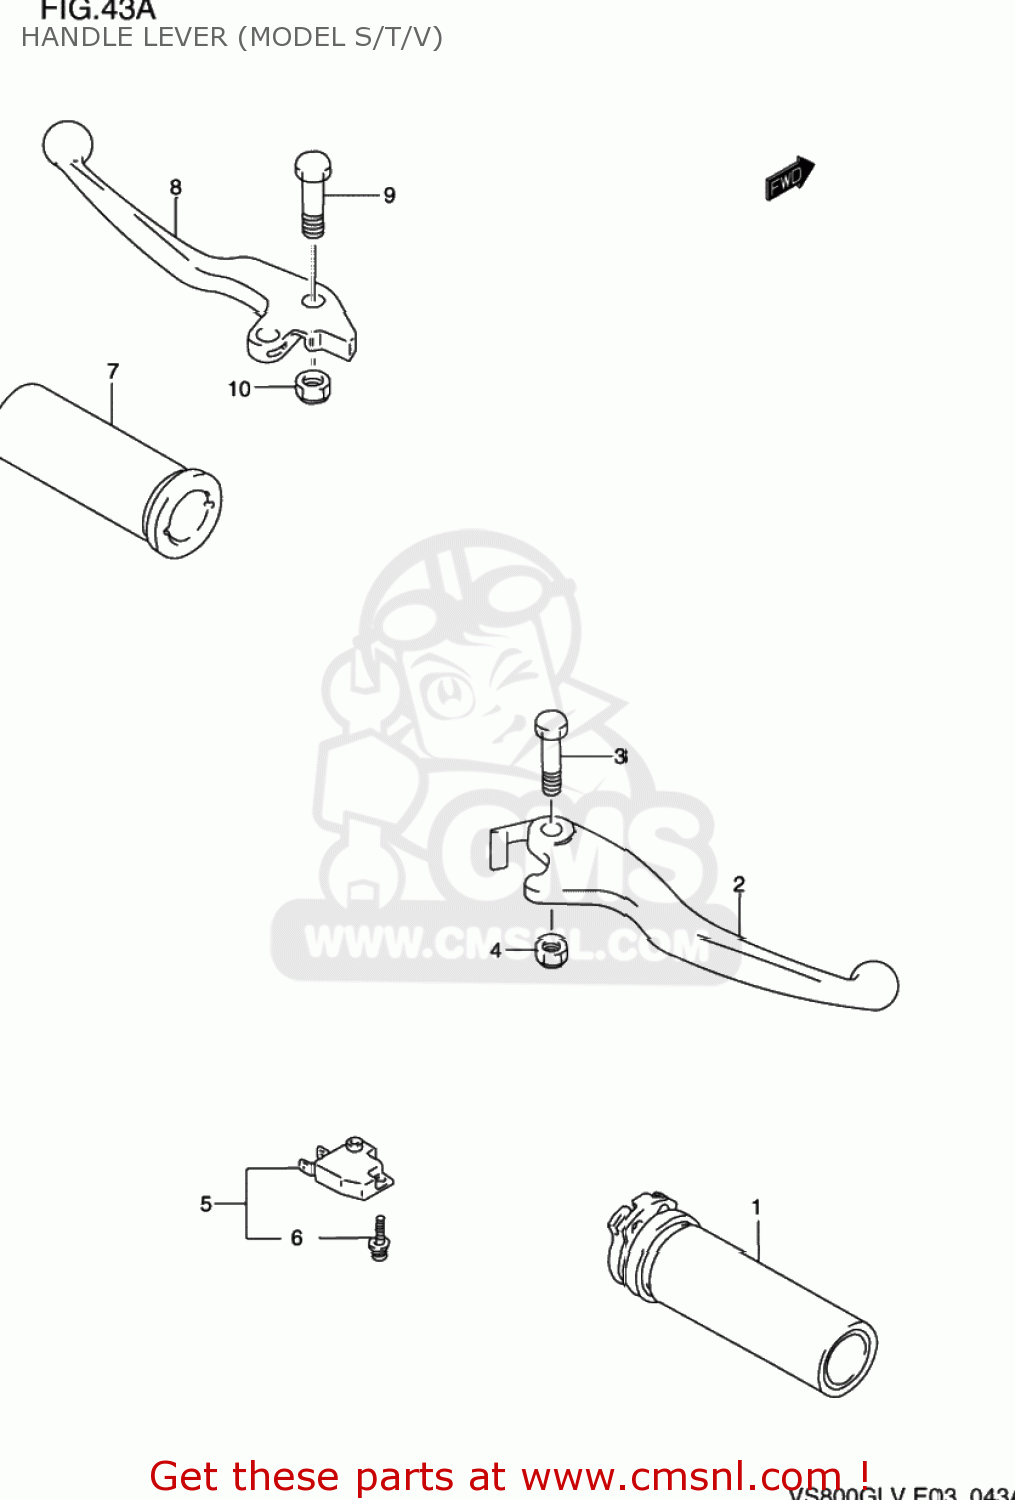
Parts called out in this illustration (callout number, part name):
1	GRIP,THROTTLE
2	LEVER,BRAKE
3	BOLT,LEVER SET
4	NUT 6MM
5	SWITCH ASSEMBLY,STOP
6	SCREW
7	GRIP,L
8	LEVER,CLUTCH (SILVER)
9	BOLT,LEVER SET
10	NUT 6MM
